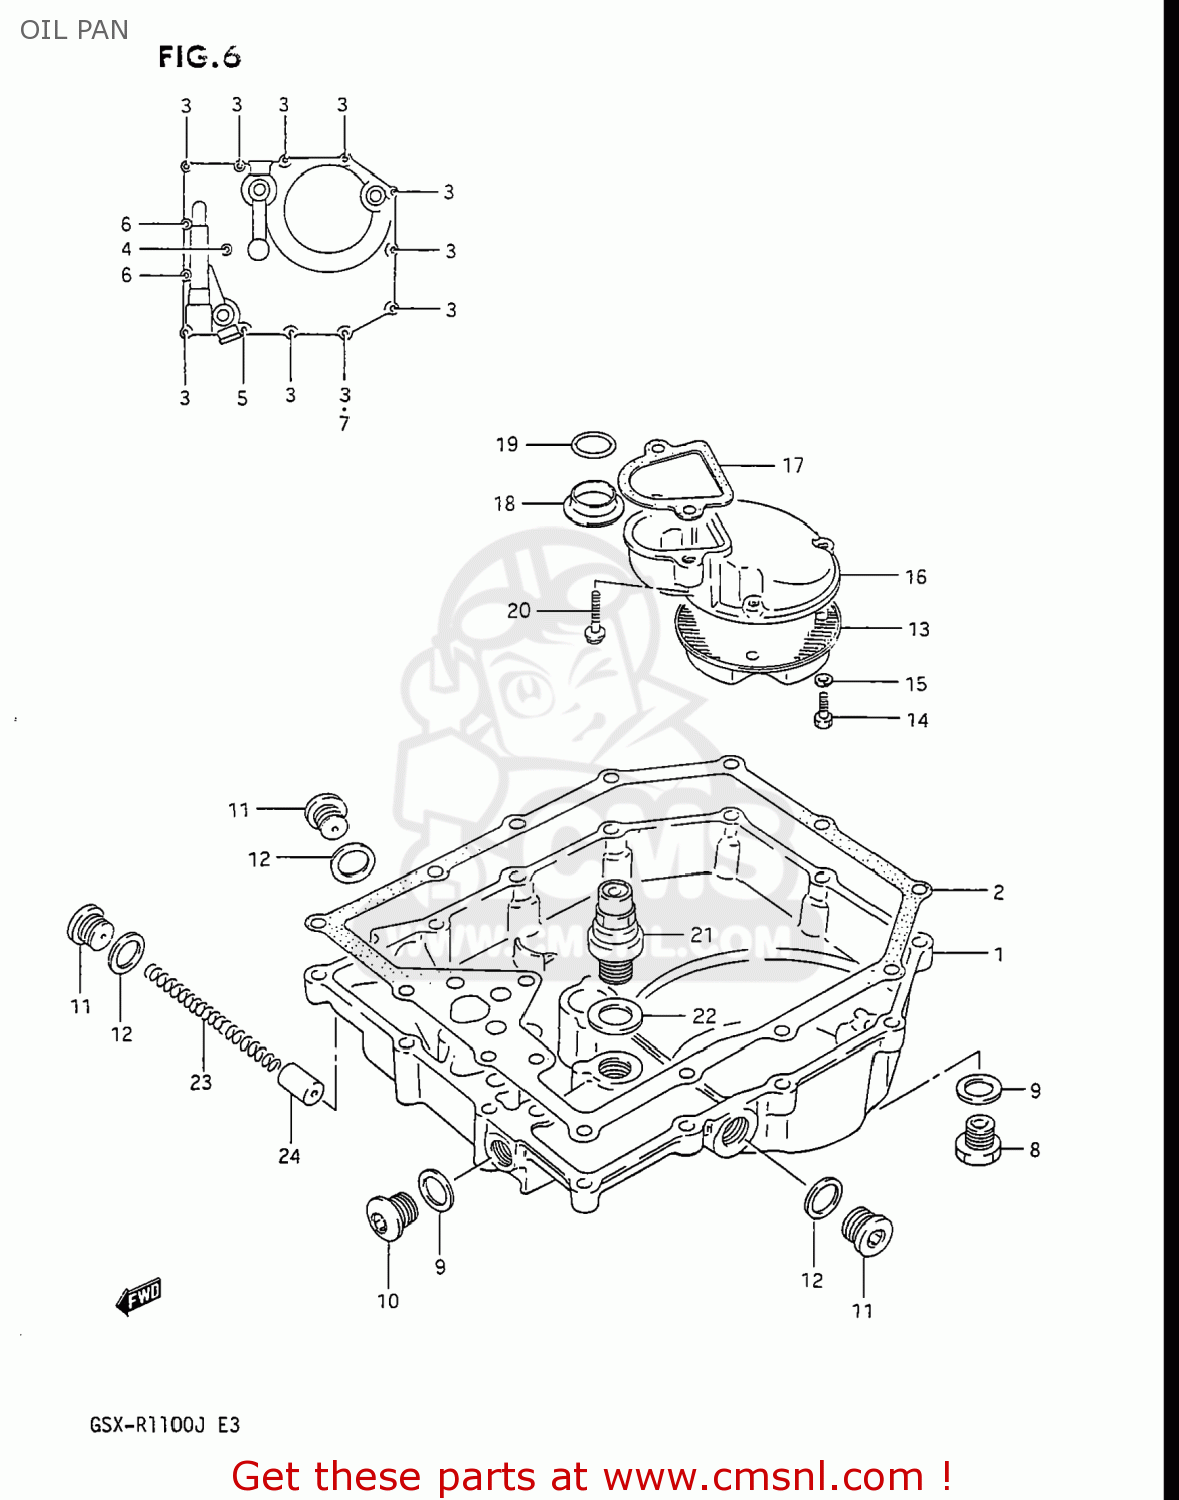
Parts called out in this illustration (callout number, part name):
1	PAN,OIL
2	GASKET,OIL PAN (NAS)
3	BOLT
4	BOLT
5	BOLT
6	BOLT
7	GASKET(5.8X11X1.2) (NAS)
8	PLUG
9	GASKET(14X19.2X2) (NAS)
10	PLUG
11	PLUG
12	GASKET(16X22X2) (NAS)
13	STRAINER,ENGINE OIL
14	BOLT
15	WASHER,LOCK
16	PROTECTOR,OIL STRAINER
17	GASKET,OIL STRAINER PROTECTOR (NAS)
18	GASKET,OIL OUTLET (NAS)
19	O RING(D:3.2,ID:17.8)
20	BOLT
21	VALVE ASSEMBLY,OIL RELIEF
22	GASKET(16X22X2) (NAS)
23	SPRING
24	PLUNGER,OIL CONTROLL
